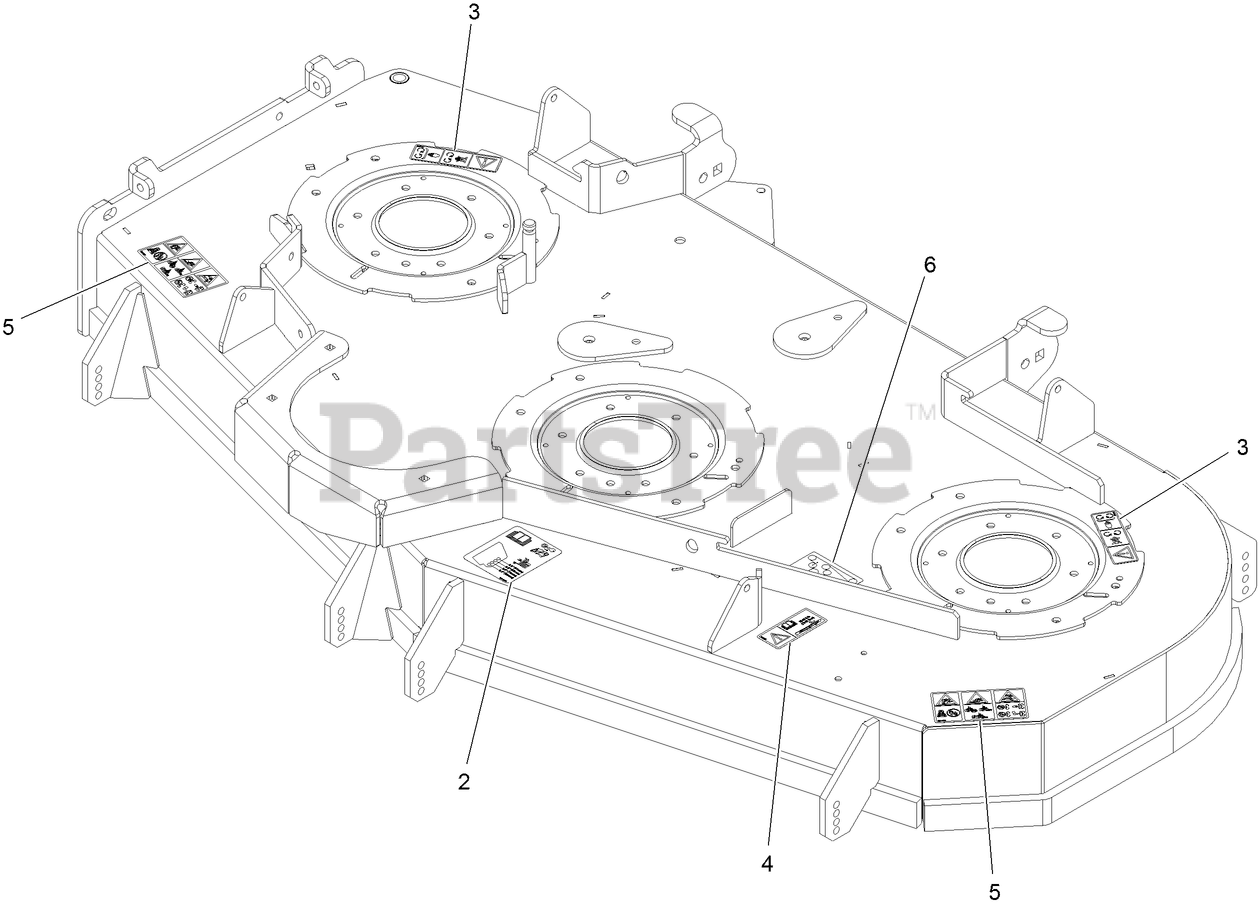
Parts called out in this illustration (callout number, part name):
2	DECAL-ROLLER, ANTI-SCALP
3	DECAL-COVER, MISSING
4	DECAL-TORQUE, BOLT
5	DECAL-DANGER THROWN OBJECTS
6	DECAL-BELT 60 SIDE
